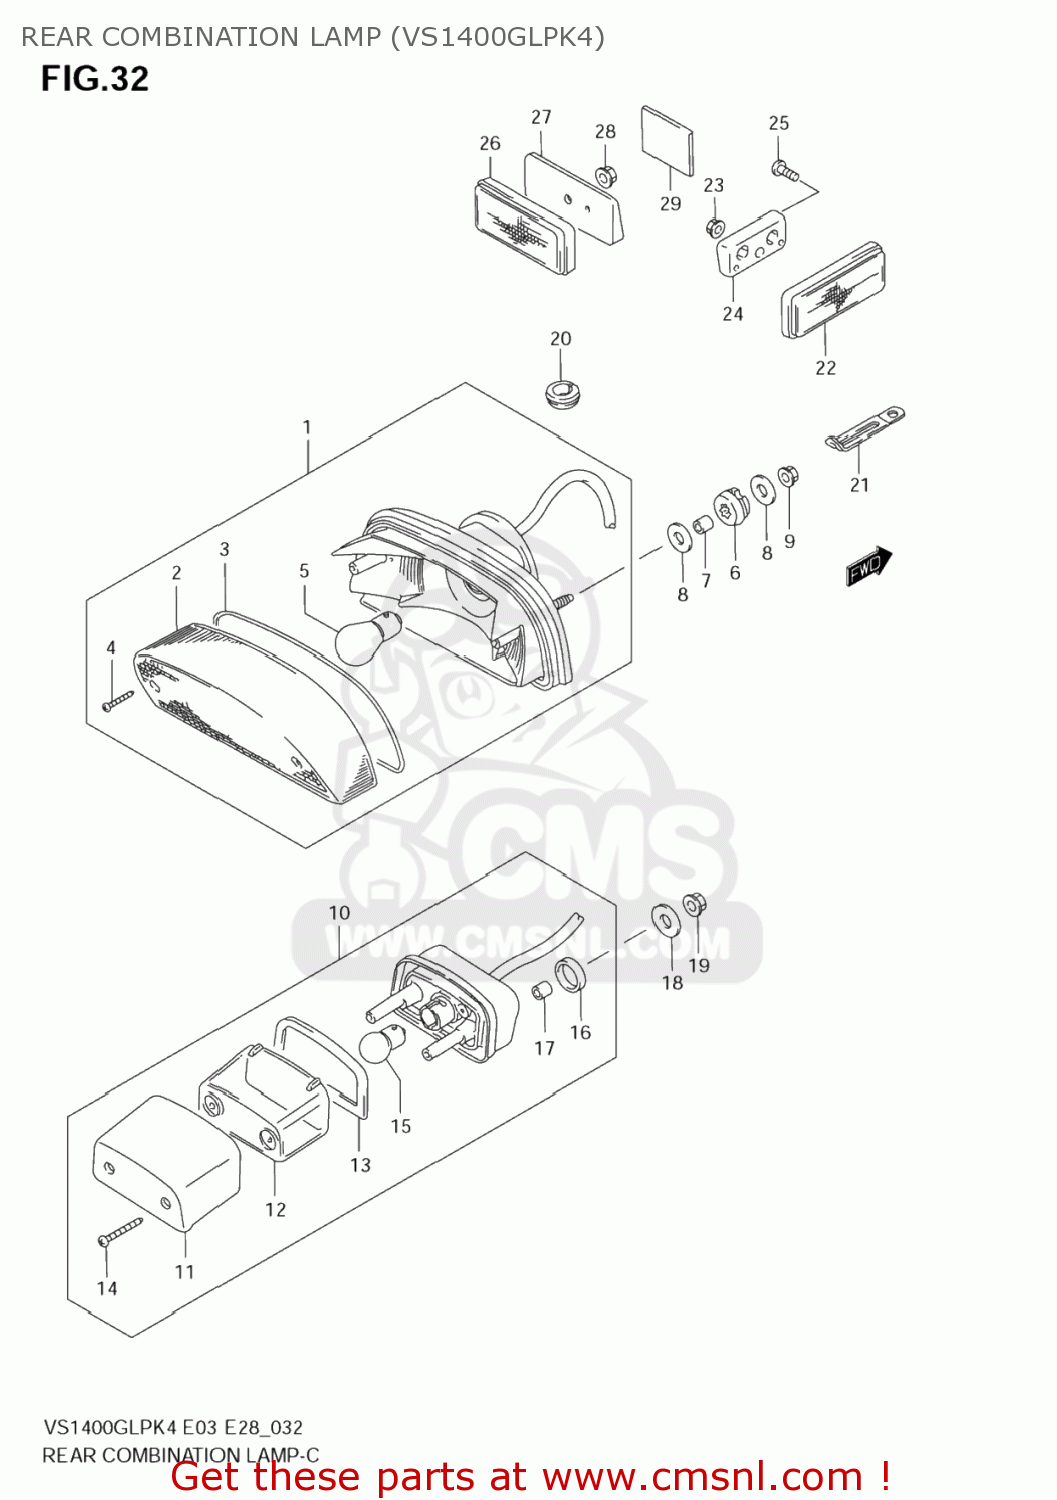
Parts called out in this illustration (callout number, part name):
1	LAMP ASSY,RR COMBINATION
2	LENS
3	GASKET (NAS)
4	SCREW
5	BULB(12V27/8W)
6	CUSHION
7	SPACER(6.5X9X10.5)
8	WASHER(6.5X20X1.2)
9	NUT
10	LAMP ASSY,LICENSE
11	COVER,LICENSE LAMP
12	LENS,LICENSE LAMP
13	GASKET,LICENSE LAMP (NAS)
14	SCREW
15	BULB(12V7.5W)
16	CUSHION
17	SPACER
18	WASHER(6.5X20X1.2)
19	NUT
20	GROMMET
21	CLAMP(L:45)
22	REFLECTOR ASSY,RR
23	NUT
24	SPACER,RR SIDE REFLECTOR
25	SCREW
26	REFLECTOR ASSY,RR
27	SPACER,RR REFLECTOR
28	NUT
29	TAPE,TOOL BAG PROTECTOR
